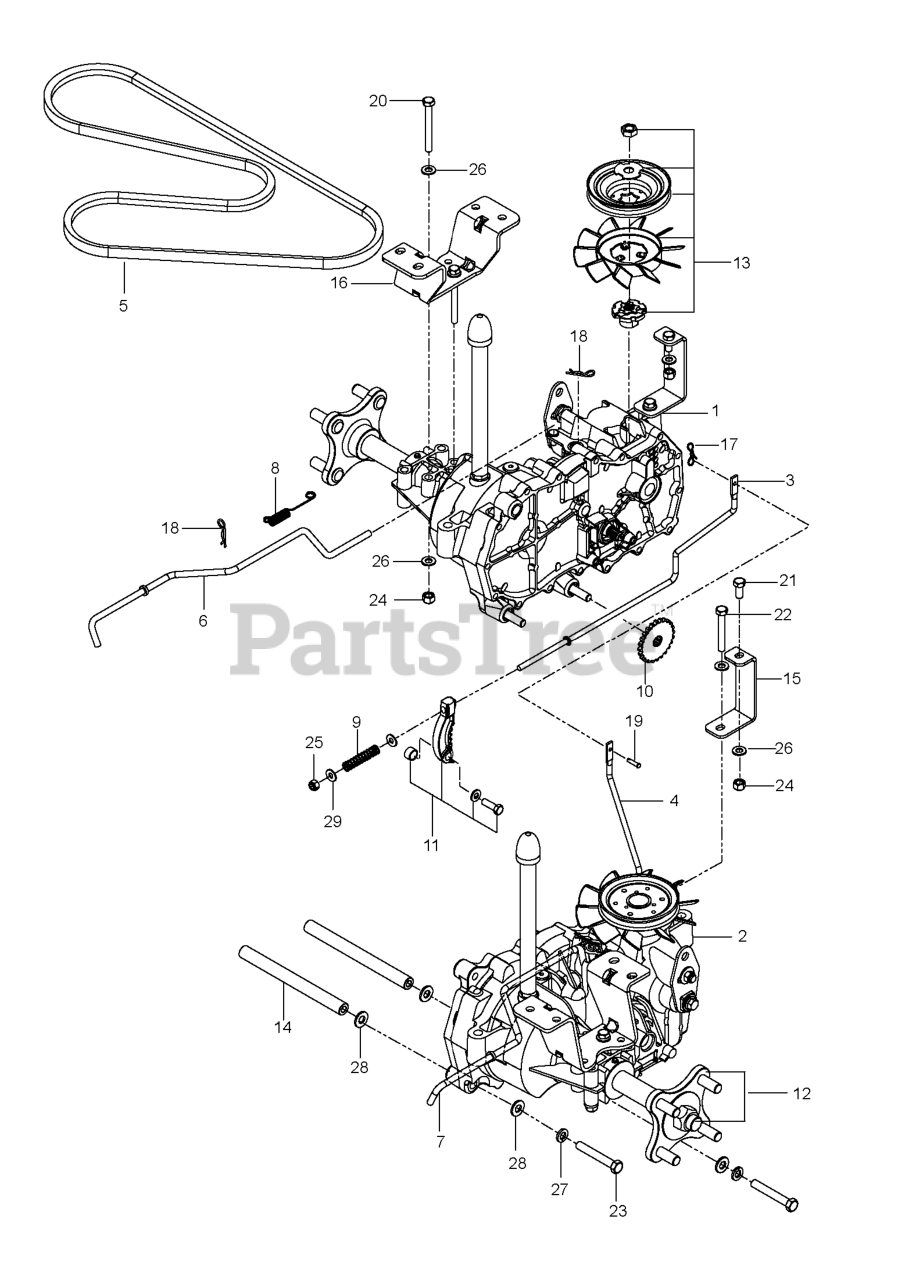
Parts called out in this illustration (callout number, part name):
1	HG_EZT, LT
2	HG_EZT, RT
3	LINKAGE.BRAKE.LT
4	LINKAGE, BRAKE RT
5	BELT, HYDRO PUMP
6	ROD.BYPASS.RZ.LH
7	ROD.BYPASS.RHT
8	SPRING.ROD.BYPASS.EZT
10	HG_DISC COG BRAKE 51635
11	HG_KIT BRAKE ARM (EZT)
12	HG_KIT, HYDRO-GEAR HUB
13	KIT FAN/PULLEY 72137
14	SPACER TUBE EZT
15	SUPPORT.FRONT.TRANS.PNTX431
16	BRACKET.EZT.MOUNT.REAR.PNTX431
17	PIN COTTER;LOCKING;BOWTIE;1IN
18	HAIRPIN #2
19	PIN.CLEVIS.3/16X.475
21	HCS 5/16C X 3/4
22	BOLT.FIN HEX 5/16-18UNC X2 1/4
23	HCS 3/8C X 2 1/2
24	NUT.71038.31-18.HEX.NYLOCK
25	NUT.1/4-20.HEX.NYLOC.ZD
26	WASHER
27	SLW 3/8 STD
27	Washers
28	WASHER
